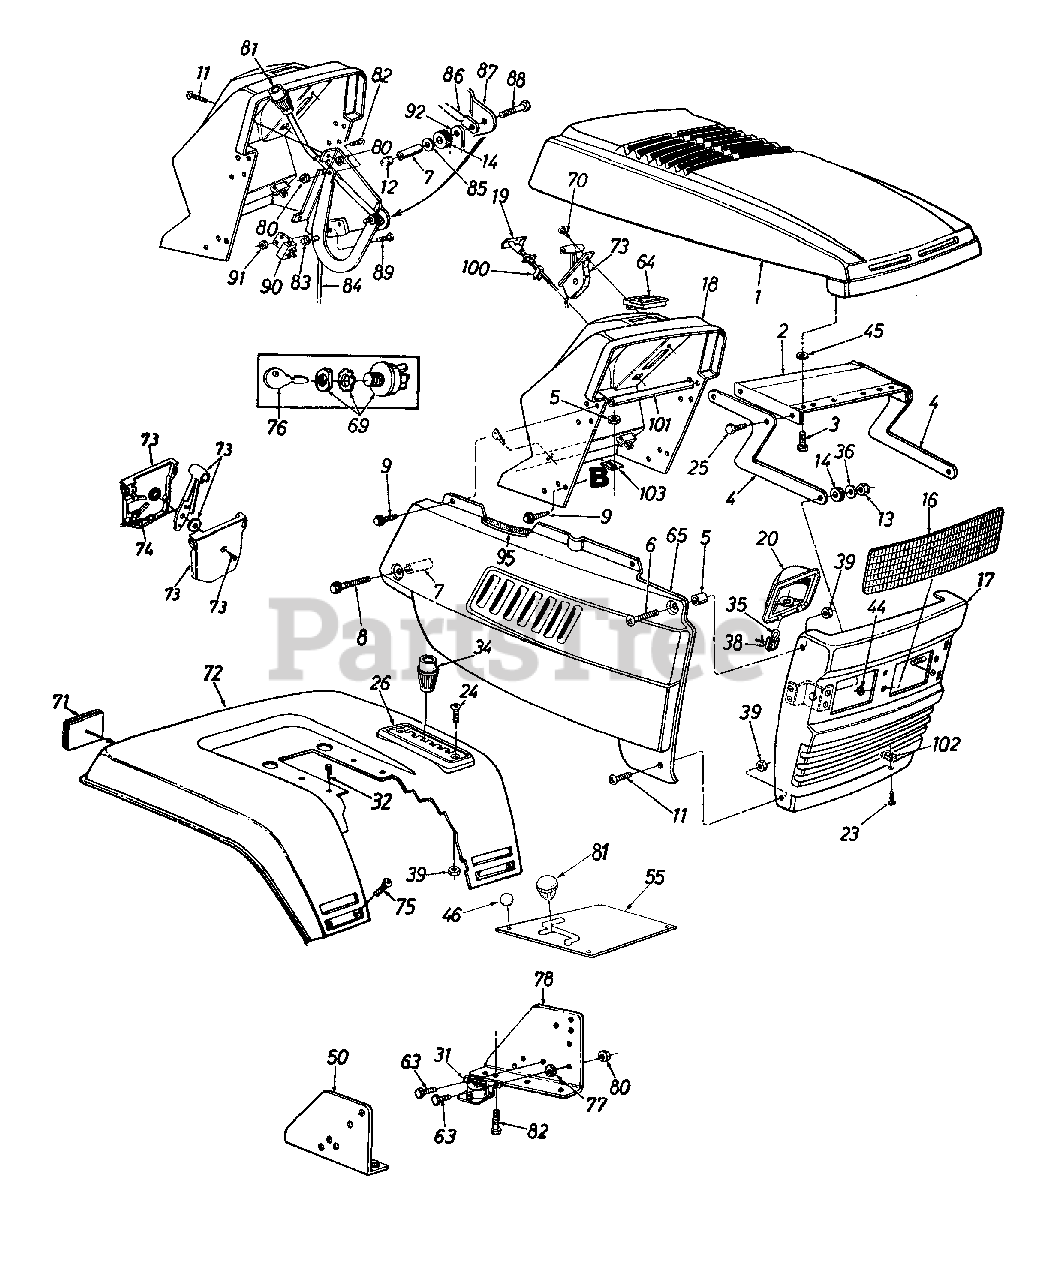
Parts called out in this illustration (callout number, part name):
1	Hood
6	Truss Hd. Mach. Scr. 1/4-20 Thd.
7	Spacer .26" I.D.
8	Hex Wash. TT-Tap Scr. 1/4-20 x 1.75" Lg
9	Hex T-Tap Scr. 1/4-20 x .75" Lg.
11	Truss Mach. Scr. 1/4-20 x .5" Lg.
12	Hex Ins. L-Nut 1/4-20 Thd.
13	Hex L-Nut 5/16-18 Thd.
14	Rubber Washer
16	Headlight Lens
19	Choke Control
20	Headlight Housing
23	Hex Bolt 5/16-18 x .75" Lg.
24	Truss Mach. Scr. 1/4-20 x .75" Lg
25	Hex Wash. Hd. Scr. 1/4" x .5" Lg.
26	6-Speed Selector Plate
31	Solenoid
32	Hex Hd. Rolling Scr. 5/16-24 x .75" Lg.
34	Shift Knob
35	Lamp
36	Bell-Wash. .34" I.D. x .87"
38	Socket
39	Hex Sems Nut 1/4-20 Thd.
44	Speed Nut 5/16" I.D.
45	Fl-Wash. .406" I.D.
46	Ball Knob
64	Ammeter
70	Truss Mach. AB-Tap Scr. #10 x .5" Lg.
71	Reflector
74	Throttle Control Wire 35" Lg.
75	Carriage Bolt 1/4-20 x .5" Lg.
76	Key
77	Ext. L-Wash. 1/4" I.D.
81	Knob
82	Hex Bolt 1/4-20 x .62" Lg.
83	Push Nut
84	PTO Rod
85	Fl-Wash. .281" I.D. x .73"
86	PTO Lever
89	Truss Mach. Scr. #10-24 x .5" Lg.
90	Safety Switch
91	Hex Nut #10-24 Thd.
92	PTO Bracket
95	Trim Strip 12" Lg.
100	Retainer Clip
101	Dash Support Tube
102	U-Nut 5/16-18 Thd.
103	Dash Panel Fastening Tab
